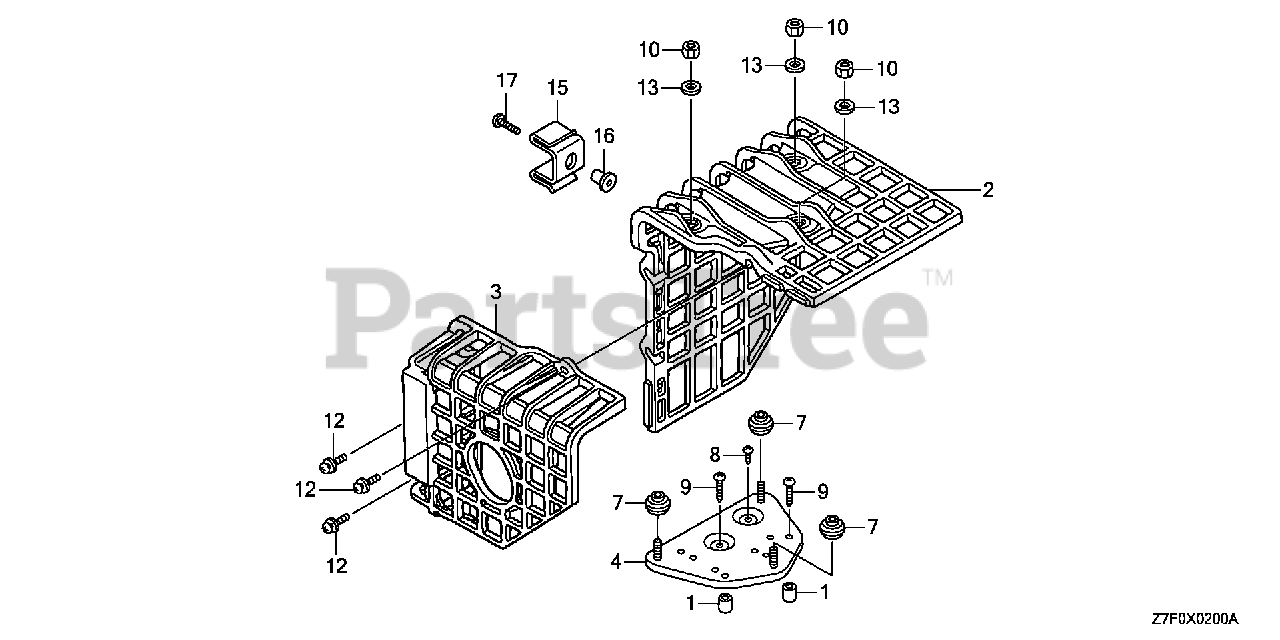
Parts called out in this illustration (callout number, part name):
1	COLLAR, AIR CLEANER HOUSING
2	COVER, MUFFLER
3	COVER, RR. MUFFLER
4	BASE, MUFFLER COVER
5	STAY, MUFFLER COVER
6	PLATE, SET
7	SPACER, MUFFLER COVER
8	SCREW, TAPPING (5X8)
9	SCREW, TAPPING (5X25)
10	NUT, HEX. (5MM)
11	SCREW-WASHER (5X12)
12	SCREW-WASHER (6X20)
13	WASHER, PLAIN (5MM)
14	WASHER, SPRING (5MM)
15	STAY, MUFFLER COVER
16	COLLAR, FAN COVER
17	SCREW, TAPPING (6X25)
